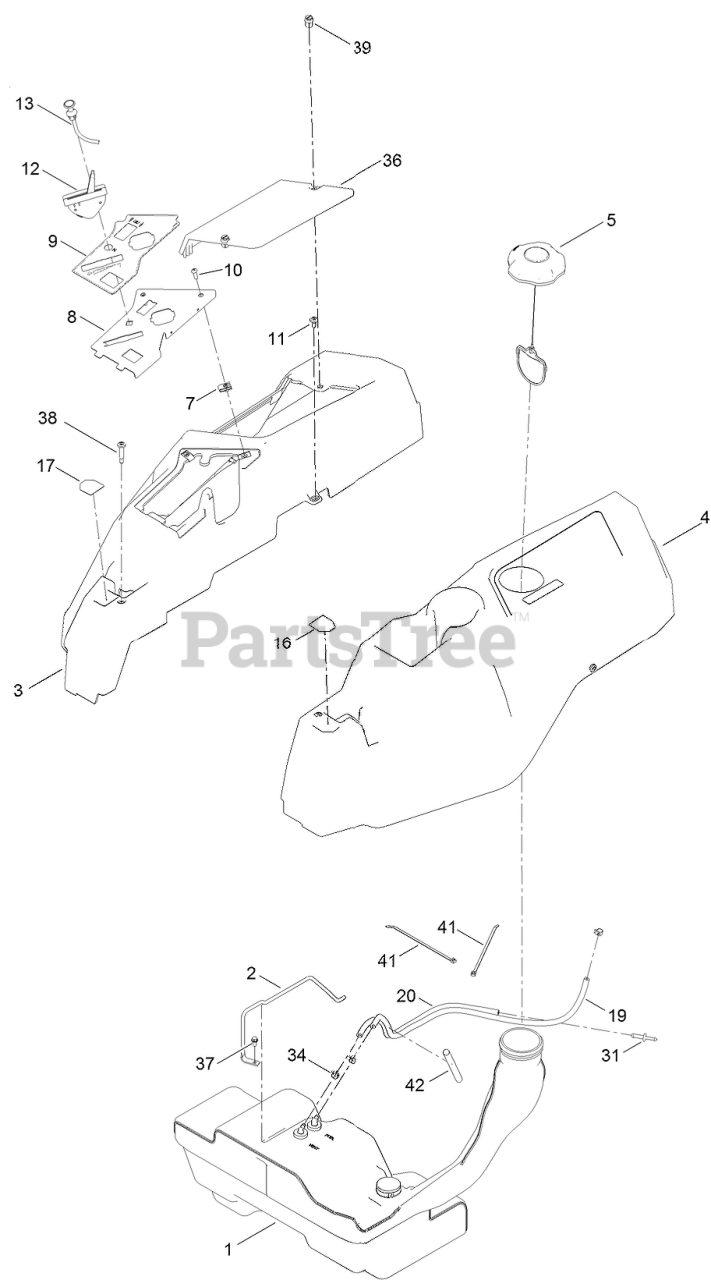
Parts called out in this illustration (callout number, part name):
1	FUEL TANK ASM
2	ROD-HOLD DOWN
3	POD-RH
4	POD-LH
5	CAP-FUEL, RATCHETING
8	PANEL-CONTROL
9	DECAL-PANEL, CONTROL
10	SCREW-PRH
11	SCREW-SHOULDER
12	CABLE-THROTTLE
13	CABLE-CHOKE
16	DECAL-LEVER, CONTROL (LH)
17	DECAL-LEVER, CONTROL (RH)
19	HOSE-FUEL
20	HOSE-FUEL
31	ADAPTOR-ORIFICE
34	CLAMP-HOSE
36	COVER-BATTERY
37	SCREW-HWH
38	SCREW-SHOULDER
39	FASTENER
41	TIE-CABLE
42	SLEEVE-FUEL LINE PROTECTOR
